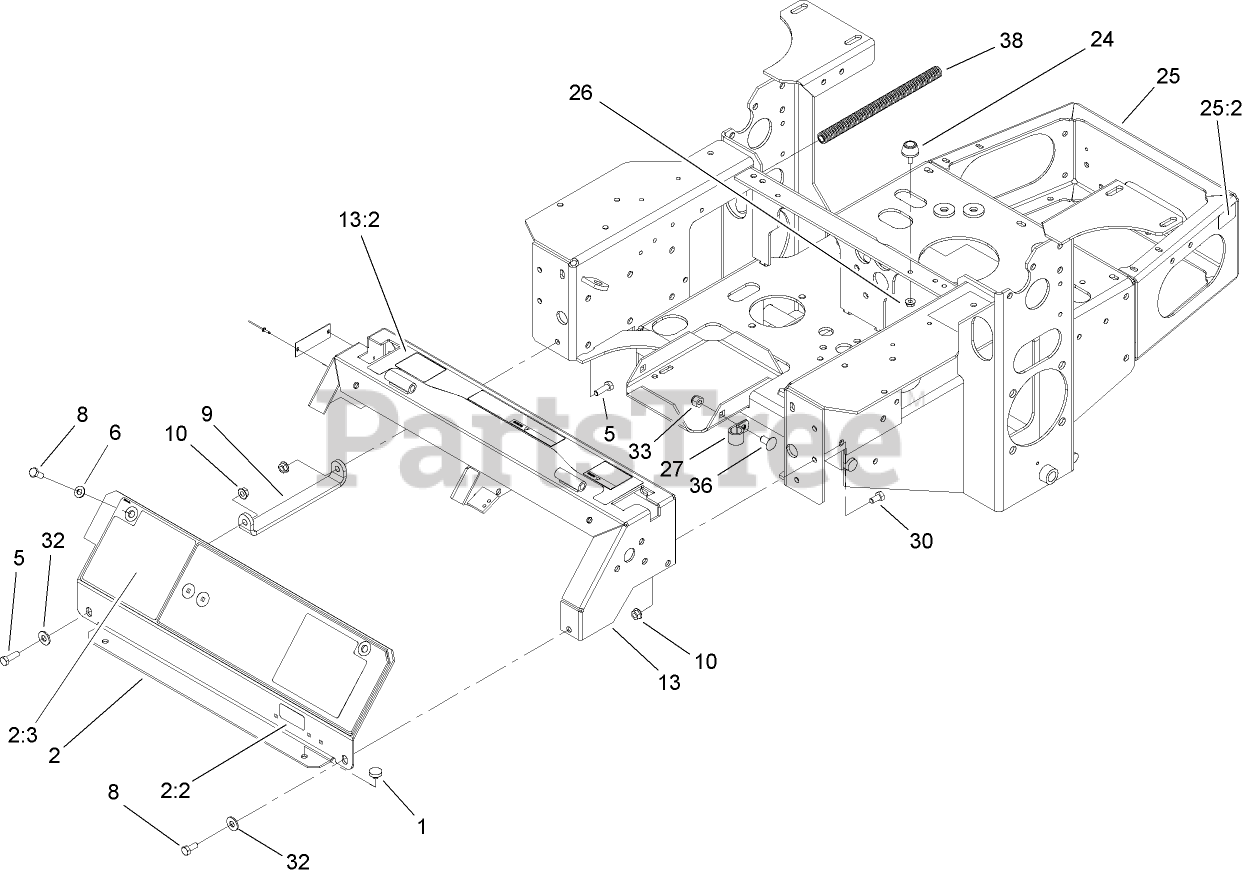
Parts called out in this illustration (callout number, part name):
1	BUMPER
2	PANEL ASM
2:2	DECAL-PROTECTION, EAR
2:3	DECAL-COVER, PANEL
5	SCREW-HH
6	WASHER-PLAIN
8	SCREW-HH
9	BRACKET
10	NUT-HF
13	CONSOLE FRAME ASM
13:2	DECAL-CONSOLE, TOP
24	BUMPER
25	MAIN FRAME ASM
25:2	DECAL-SURFACE, HOT
26	NUT-HF
27	CLIP-LOOM
30	SCREW-HH
32	WASHER-FLAT
33	NUT-LOCK, NI
36	SCREW-CARR
38	CONDUIT-CONVOLUTED, SPLIT
